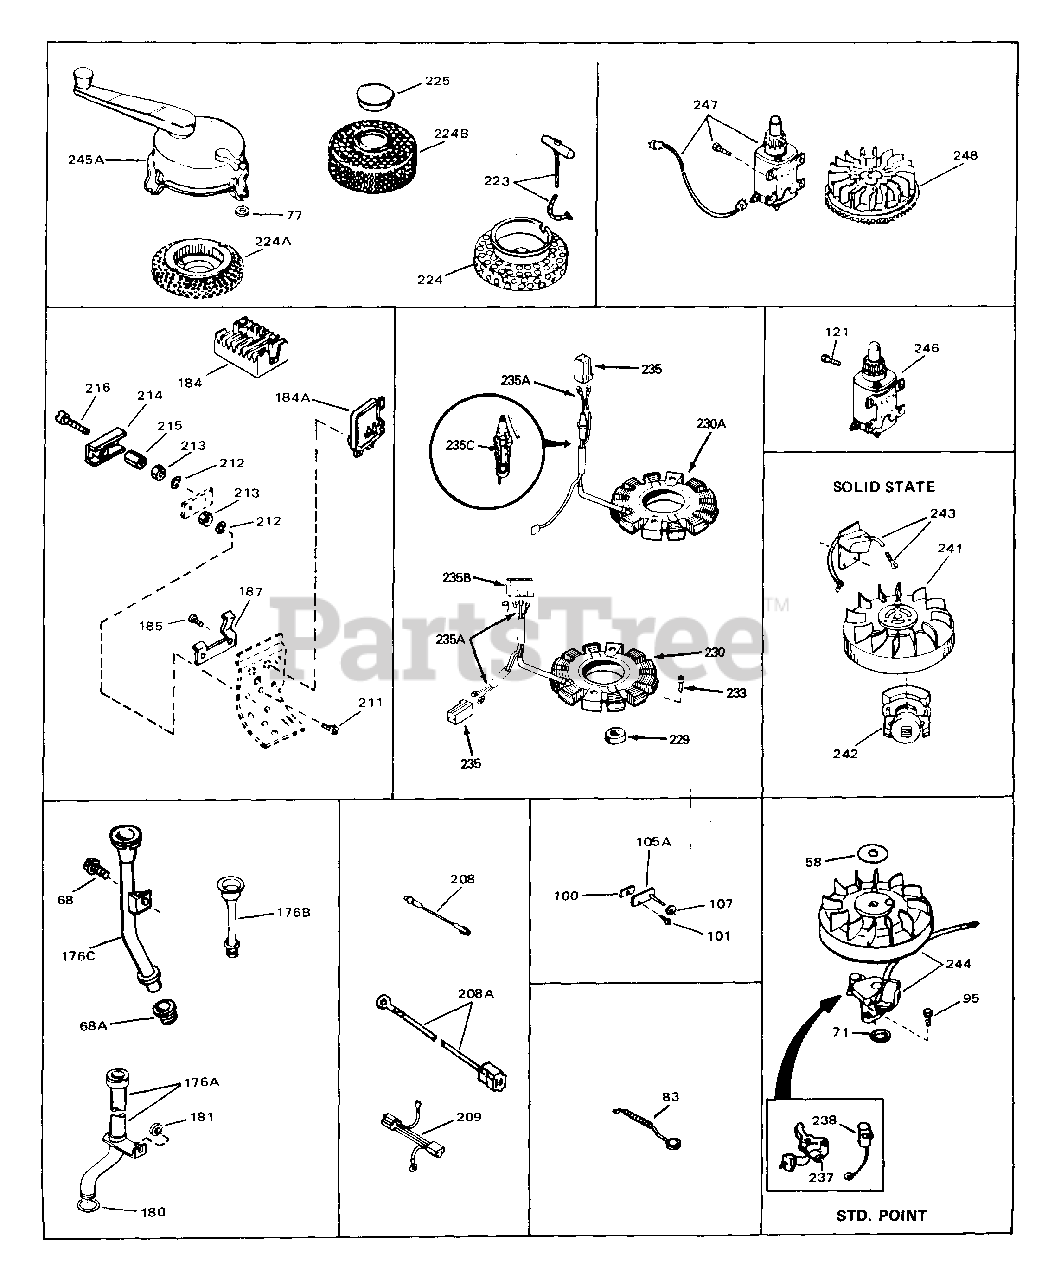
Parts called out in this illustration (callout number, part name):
77	Washer, Thrust
95	Screw, Hex hd. Sems, 1/4-20 x 5/8 (St d.
95	Screw, Hex hd. Sems, 1/4-20 x 1-1/8 ( Std.
107	Washer, Flat
121	Screw, Hex washer hd., Sems, 1/4-20 x 1/2
121	Screw, Hex hd. Sems, 1/4-20 x 1/2
209	Harness Assy., Adapter
237	Contact Assy., Breaker
238	Condenser
244	Magneto, Tecumseh
247	Starter Motor Kit (110-120 Volt)
248	Flywheel (Std. Point) (V70 thru type letter
248	Flywheel (Std. Point) (V70 type lette r D)
248	Flywheel (Solid state ignition)
